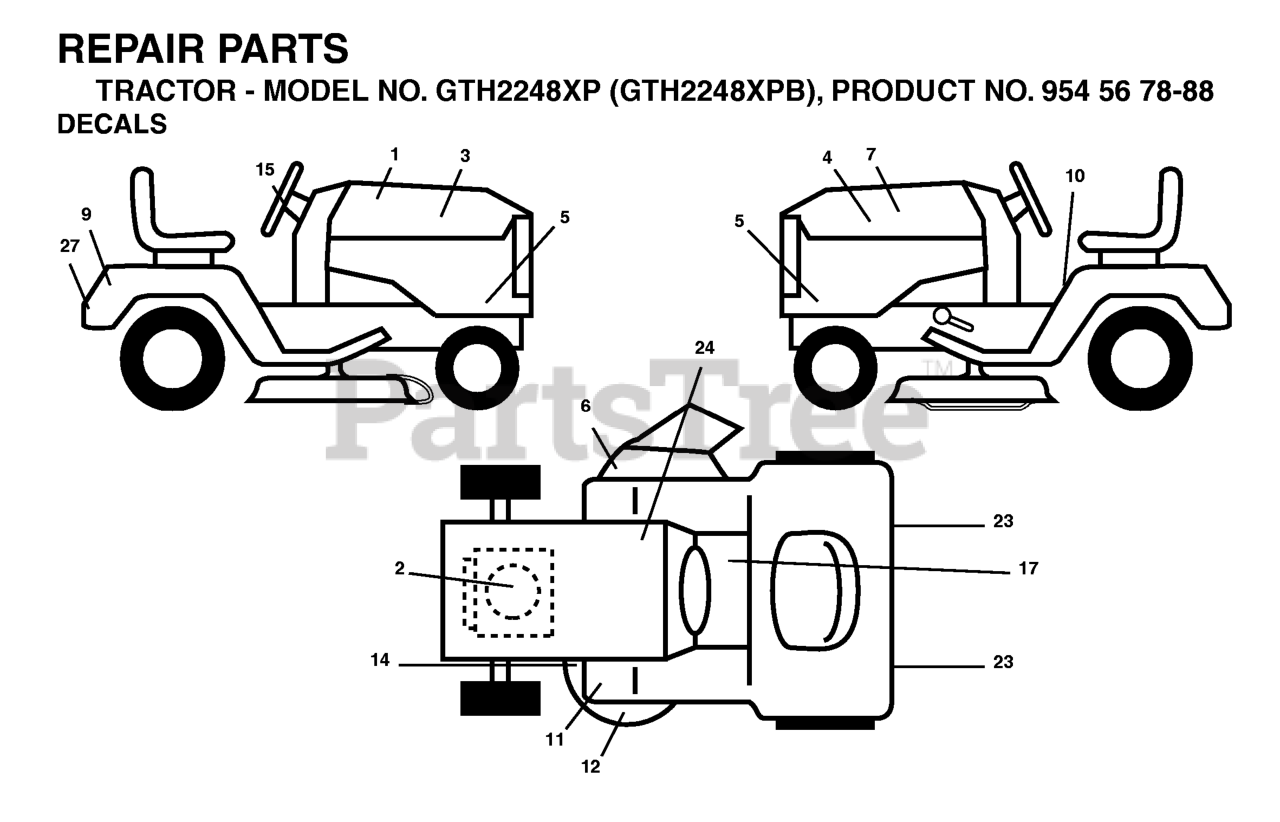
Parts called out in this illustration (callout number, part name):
5	DECAL HOOD SIDES
6	DECAL.WARN.KEEP.HAND.AWAY
7	DECAL HOOD CUST. RESP.
9	DECAL, FENDER
10	DECAL FENDER DANGER
11	DECAL, FOOTREST
12	DECAL CLUTCH/BRAKE
14	DECAL V-BELT SCHEMATIC
15	DECAL.WHEEL.STEERING.HUSQ.PERM
23	REFLECTOR-TAIL YT
24	DECAL BTRY SYMBOLS
27	DECAL.BYPASS.FENDER.CRD.LT.YT
